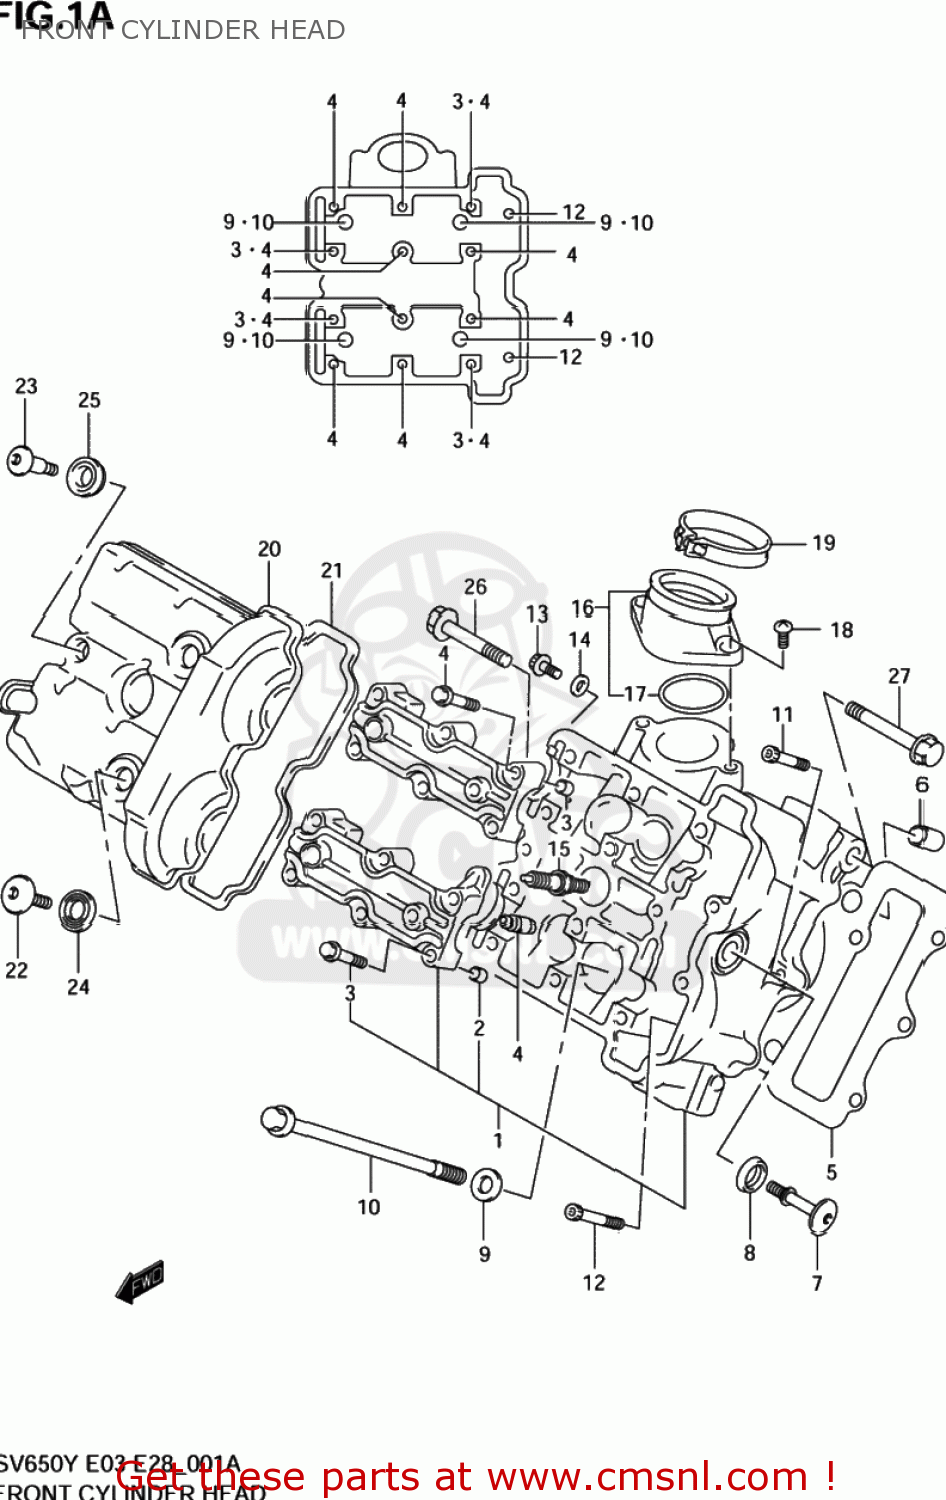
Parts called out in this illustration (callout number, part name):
1	HEAD ASSY,CYLINDER FR
2	PIN(6.2X8X11)
3	BOLT(6X39)
4	GUIDE,VALVE
5	GASKET,CYLINDER HEAD (NAS)
6	PIN
7	BOLT,CYL HEAD SIDE FACE
8	WASHER,HEAD COVER
9	WASHER(10.5X19X2)
10	BOLT(10X160)
11	BOLT
12	BOLT(6X70)
13	BOLT
14	GASKET(5.8X13X1.2) (NAS)
15	PLUG,SPARK(CR8E)
16	PIPE ASSY,INTAKE FR
17	O RING(D:2.4,ID:47X42)
18	SCREW ,6X16
19	CLAMP
20	COVER,CYLINDER HEAD FR
21	GASKET,CYLINDER HEAD COVER (NAS)
22	BOLT(7X17.5)
23	BOLT(7X31)
24	WASHER(10.6X25.5X2.3)
25	CUSHION,HEAD COVER BOLT
26	BOLT
27	BOLT
